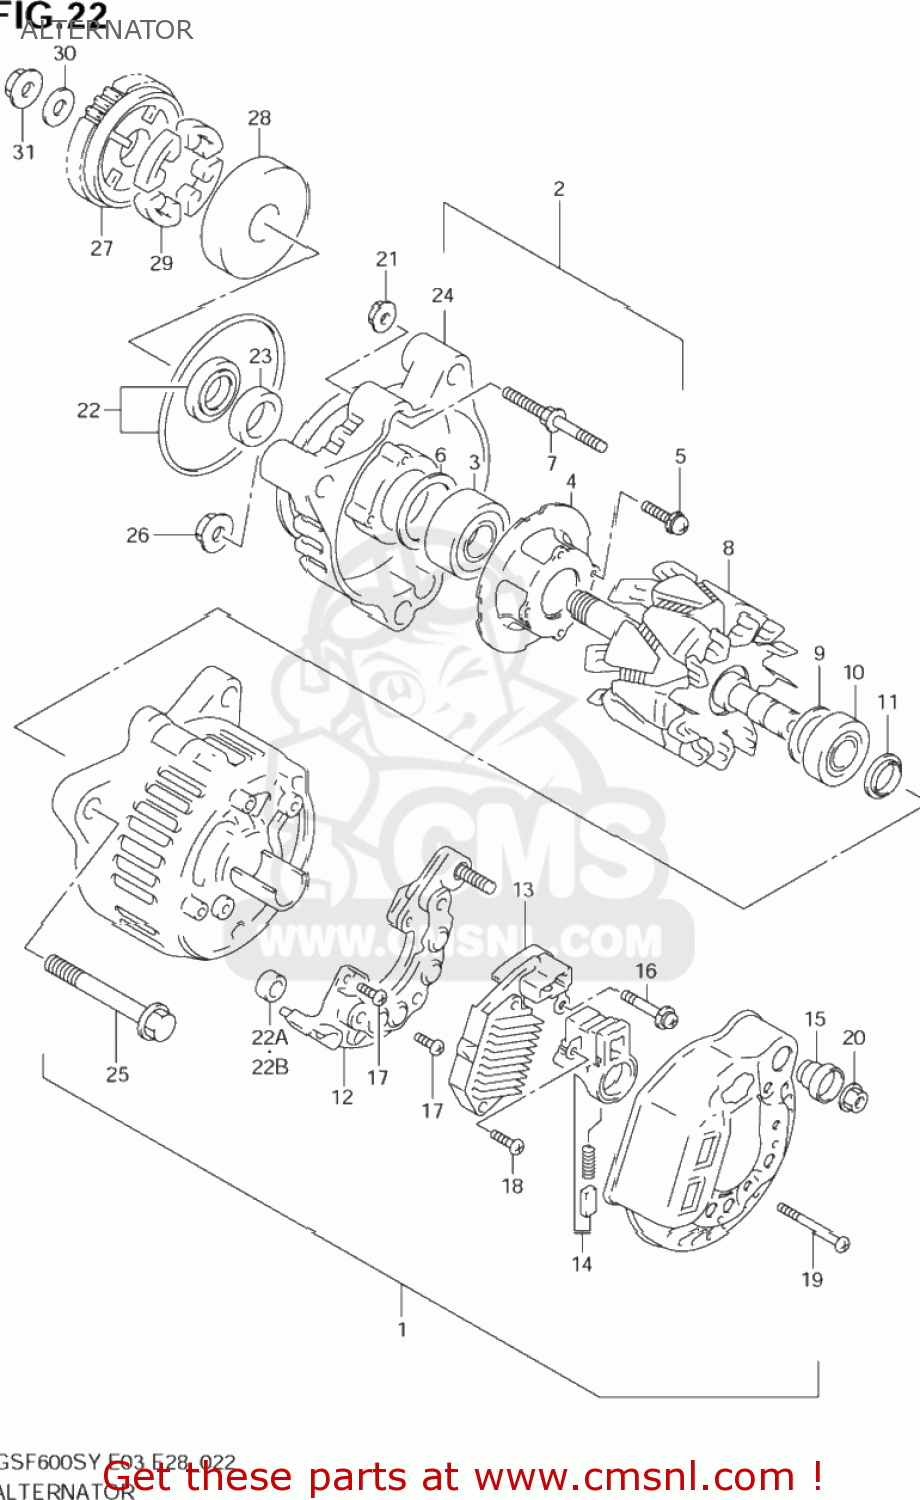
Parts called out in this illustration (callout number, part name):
1	ALTERNATOR ASSEMBLY
2	FRAME,DRIVE END
3	BEARING
4	RETAINER
5	SCREW(4X14)
6	COVER,BEARING
7	STUD BOLT
8	ROTOR ASSY
9	COVER,BEARING
10	BEARING
11	COVER(2)
12	HOLDER,RECTIFIER
13	REGULATOR ASSY
14	HOLDER,BRUSH
15	INSULATOR,TERMINAL
16	SCREW
17	SCREW 4X6
18	SCREW
19	SCREW
20	NUT
21	NUT
22	SERVICE KIT(A)
22A	SERVICE KIT,B
22B	SERVICE KIT(B)
23	SPACER
24	FRAME,END
25	BOLT
26	NUT
27	GEAR,GENERATOR DRIVEN
28	HOUSING,GENERATOR GEAR DAMPER
29	DAMPER,GENERATOR DRIVEN
30	WASHER
31	NUT
